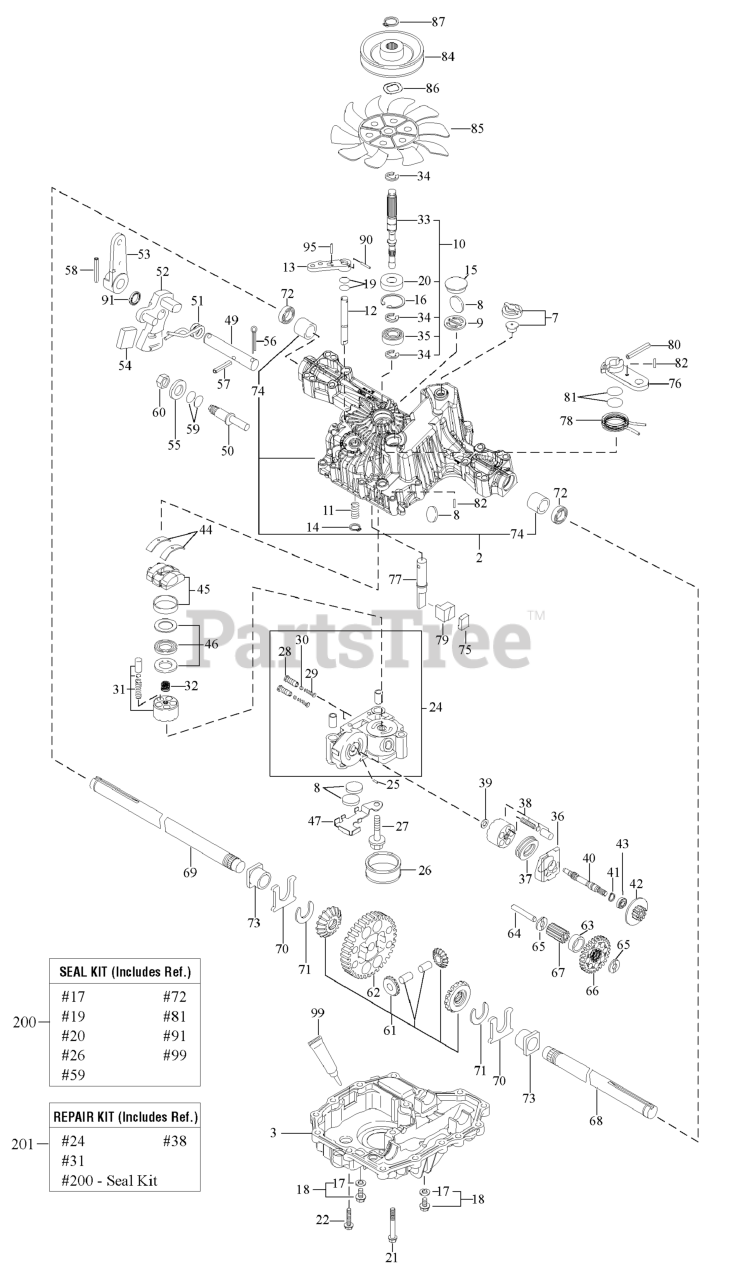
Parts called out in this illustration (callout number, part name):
1	TRANSMISSION ASSEMBLY, Tuff Torque, K46BP
2	*KIT, Upper Case
3	*LOWER CASE
7	VENT VALVE 15
9	*MAGNET HOLDER
10	*PUMP SHAFT/BEARING KIT
12	BYPASS SHAFT A
13	LEVER, Bypass
14	RING, Snap, 10
15	SEALING CAP, 30
16	RING, Snap, C 35
17	SEAL WASHER, 8
18	KIT, Drain Bolt
22	SCREW, Tapping, 8 * 30
24	CENTER CASE E W/BALL IDS SERVICE KIT
25	PIN, 3 * 9.8
27	BOLT, 10 * 75
29	IDS SPRING
31	KIT, Cylinder Block (Pump)
33	PUMP SHAFT
34	E-RING, 15
36	MOTOR HOUSING
38	KIT, Cylinder Block
39	WASHER, 12 * 24 * 1
40	MOTOR SHAFT
41	RING, Snap, S15
42	BRAKE DISC/MOTOR GEAR (11T)
44	THRUST METAL
45	SWASH PLATE CMP
49	CONTROL SHAFT
50	FULCRUM
51	SPRING, Torsion
52	CONTROL ARM A
53	CONTROL LEVER C
54	JERKY PLATE
55	WASHER, 12
56	COTTER PIN, 1/8 * 3/4
57	SPRING PIN 6 * 36
58	ROLL PIN 6 * 40
61	*KIT, Differential Gear
63	*FINAL PINION COLLAR
64	*REDUCTION SHAFT
65	WASHER, 12 * 32 * 3.2
68	AXLE SHAFT, Left
69	AXLE SHAFT, Right
70	*THRUST WASHER
71	RING, 17
72	SEAL, 19 * 32 * 8
73	BUSHING, 19 * 25
75	BRAKE SHOE
76	BRAKE LEVER
77	*BRAKE SHAFT
78	*BRAKE RETURN SPRING
79	BRAKE ACTUATOR
80	SPRING PIN, 5 * 32
82	SPRING PIN 4 * 16
84	PULLEY D
85	FAN, White
86	WASHER, Wave
87	RING, Snap
99	*SEALANT
200	*K46 & T40 SEAL KIT (ALL MODELS)
